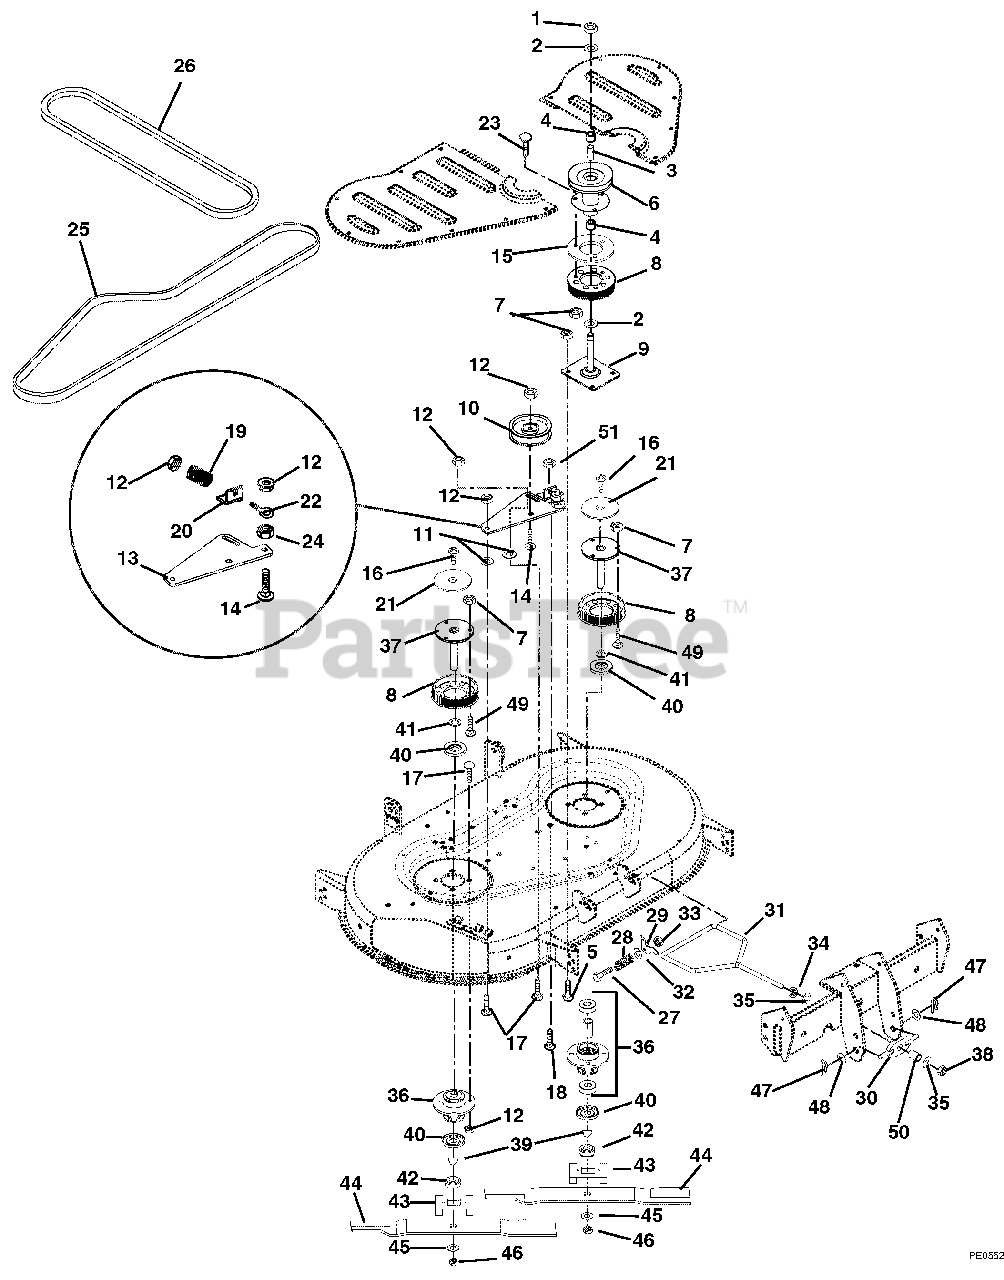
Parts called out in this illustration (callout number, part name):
1	Nut-Locking-Nylon .625-18
2	Washer-Flat-Steel .630 x 1.00 x .062
3	Spacer .64 x .88 x 4.07
4	Bearing .625 x 1.37 x .43
5	Bolt-Round Head Square Neck .31-18 x .75
6	Jackshaft
7	Nut-Locking-Top-Flange .31-18
8	Sprocket-Drive
9	Weldment-Plate Mount
10	Assembly-Idler Pulley
11	Washer-Flat-Steel .38 x 1.50 x .188
12	Nut-Locking-Top-Flange .38-16
13	Arm-Idler
14	Bolt Round Head Square Neck .38-16 x 1.75 Grade5
15	Spacer, Sprocket
16	Screw-Tapping .25-20 x .75 Hex Washer Head
17	Bolt-Round-Head Square Neck .38-16 x 1.25 Grade 5
18	Bolt-Round-Head Square Neck .38-16 x .75 Grade 5
19	Spring-Compression .125 x .78 x 1.25
20	Bracket-Belt Adjustment
21	Retainer, Belt
22	Bolt-Eye .375-16 x 2.50
23	Bolt-Round Head Square Neck .31-18 x 1.25 Grade 5
24	Nut-Locking-Nylon .38-16
25	Belt-Cog
26	V-Belt 5L-Section
27	Bolt-Hex .25-20 x 1.25 Grade 5
28	Spring-Compression .058 x .68 x .75
29	Retainer-Brace
30	Weldment-Front Mount
31	Rod Link
32	Washer-Flat-Steel .312 x .734 x .065
33	Nut-Locking-Nylon .25-20
34	Nut-Locking-Center .50-13
35	Washer-Flat-Steel .563 x 1.38 x .109
36	Assembly-Spindle Housing
37	Weldment-Spindle Shaft
38	Nut-Locking-Nylon .50-13
39	Key Woodruff .188 x .625 x .31
40	Bearing-Slinger
41	Washer-Flat-Steel .755 x 1.25 x .125
42	Hub-Retainer
43	Tray-Blade
44	Blade, 22"
45	Washer-Locking .75 x .188
46	Nut-Jam .75-10
47	Clip-Spring
48	Washer-Flat-Steel .531 x 1.06 x .095
49	Bolt-Round-Head Square Neck .31-18 x 1.00 Grade 5
50	Bushing-Sleeve .50 x .74 x .53
51	Nut-Locking-Jam-Center .375-16
